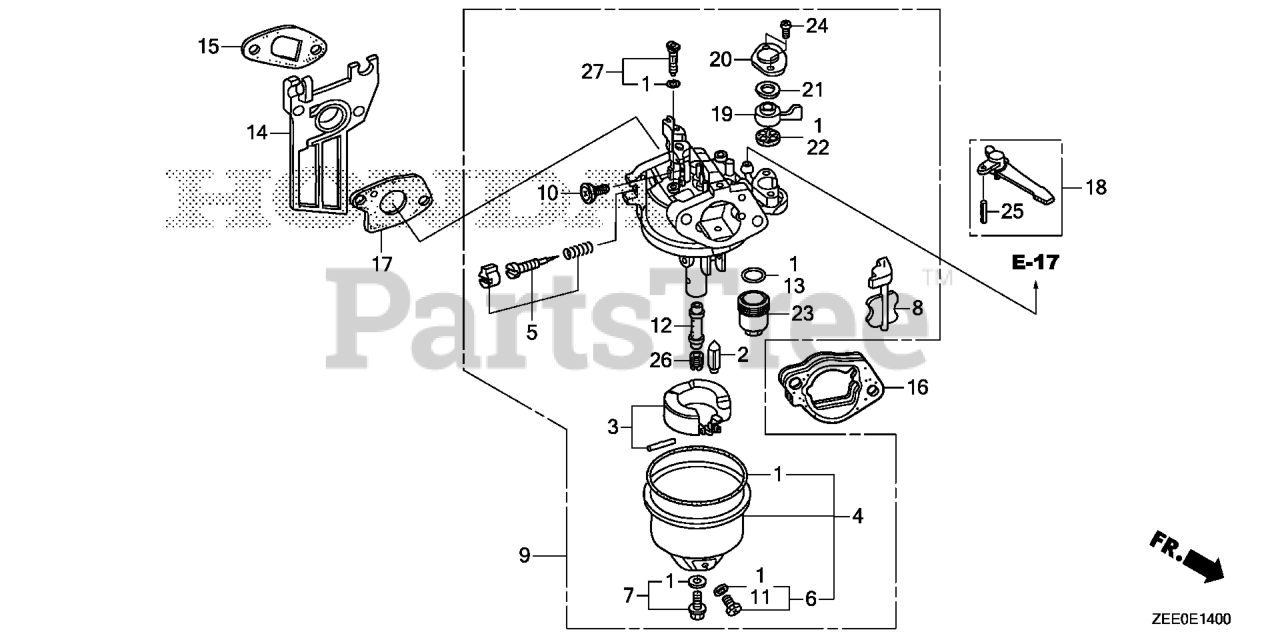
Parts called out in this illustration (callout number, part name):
1	GASKET SET
2	VALVE SET, FLOAT (CARBURETOR NO.) (SEAT NOT INCLUDED)
3	FLOAT SET
4	CHAMBER SET, FLOAT
5	SCREW SET (CARBURETOR NO.)
6	SCREW SET, DRAIN
8	CHOKE SET (CARBURETOR NO.)
9	CARBURETOR ASSY. (BEA3Q A)
10	SCREW, THROTTLE STOP
11	WASHER, PLAIN (6.2X10.7 DRAIN) (CARBURETOR NO.)
12	NOZZLE, MAIN
13	GASKET, FUEL STRAINER CUP
14	INSULATOR, CARBURETOR
15	GASKET, INSULATOR
15	GASKET, INSULATOR (NINGBO SIL GASKET)
16	SPACER, CARBURETOR
17	GASKET, CARBURETOR
17	GASKET, CARBURETOR (NINGBO SIL GASKET)
18	LEVER, CHOKE (STD)
19	LEVER, PETCOCK
20	PLATE, LEVER SETTING (CARBURETOR NO.)
21	SPRING, PETCOCK LEVER (CARBURETOR NO.)
22	GASKET, VALVE
23	CUP, FUEL STRAINER
24	SCREW, PAN (3X6)
25	PIN, SPRING (2X12)
26	JET, MAIN (#70)
26	JET, MAIN (#72)
26	JET, MAIN (#75)
27	JET SET, PILOT (#38)
